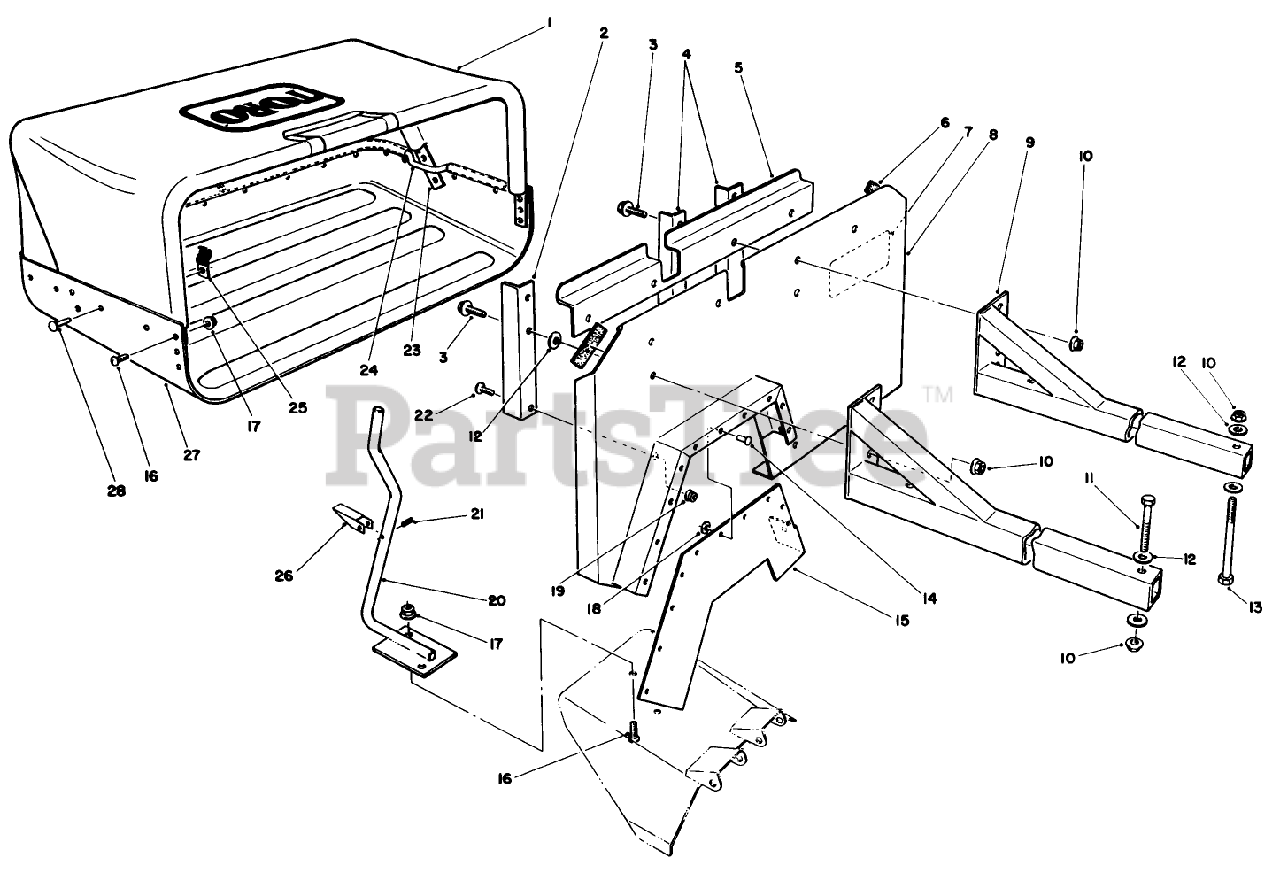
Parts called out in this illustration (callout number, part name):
3	SCREW-HHF
6	PAD-RUBBER
7	DECAL-DANGER
10	NUT-HHF, WHIZ
11	SCREW-HH
12	WASHER-FLAT
13	SCREW-HH
14	RIVET-POP
15	EXTENSION-RUBBER
16	SCREW-PPH
17	NUT-HF
18	WASHER-PLAIN
19	NUT-LOCK, HHF
21	PIN-SPRING
24	ROD-CLOTH
25	CLIP-HALF
26	LATCH-LOCKUP
27	TRAY-BAG, GRASS
28	RIVET-BLIND
